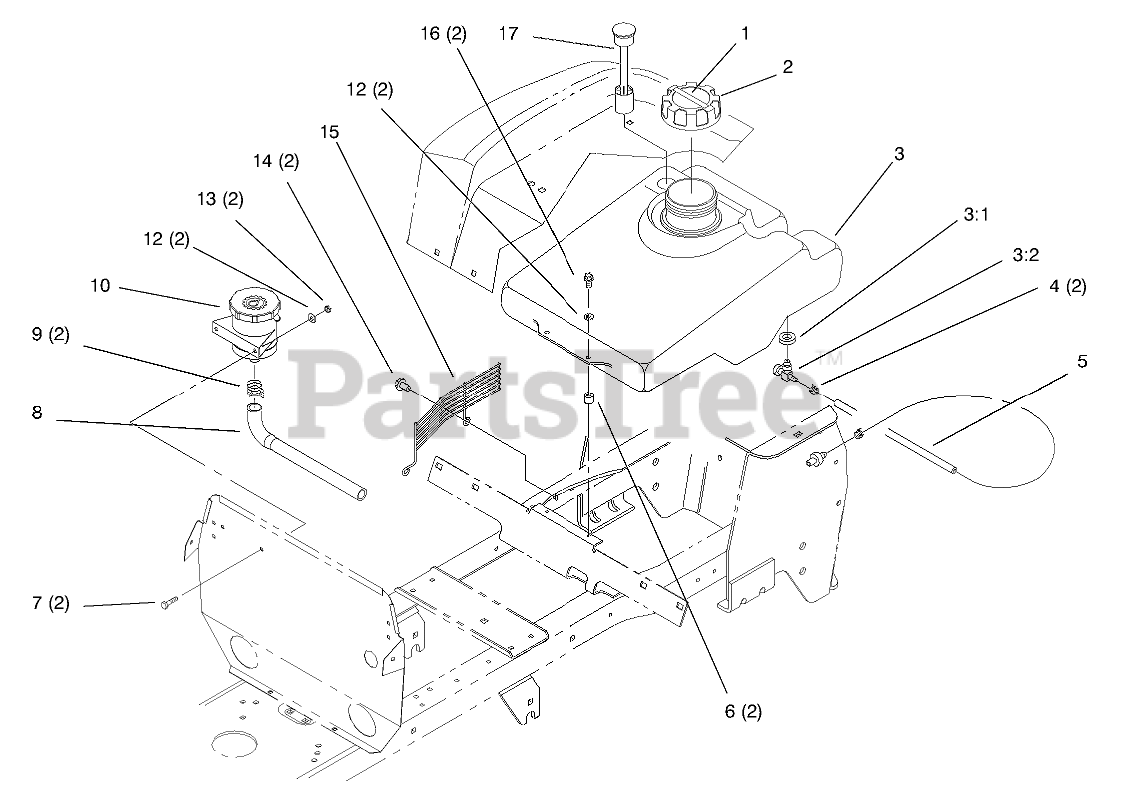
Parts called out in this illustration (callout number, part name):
2	GAS CAP ASM
3	TANK-GAS
3:1	BUSHING
3:2	VALVE-FUEL
4	CLAMP-HOSE
5	HOSE - FUEL LINE TWIN
6	SPACER - FUEL TANK
7	SCREW-HH
8	HOSE - HYDRO
9	CLAMP-HOSE
10	ASS'Y-RESERVOIR
12	WASHER-FLAT
13	NUT-LOCK, NI
14	Screw-HWH (Only On: 70264)
15	Guard-Fan (Only On: 72064)
16	SCREW-HH
